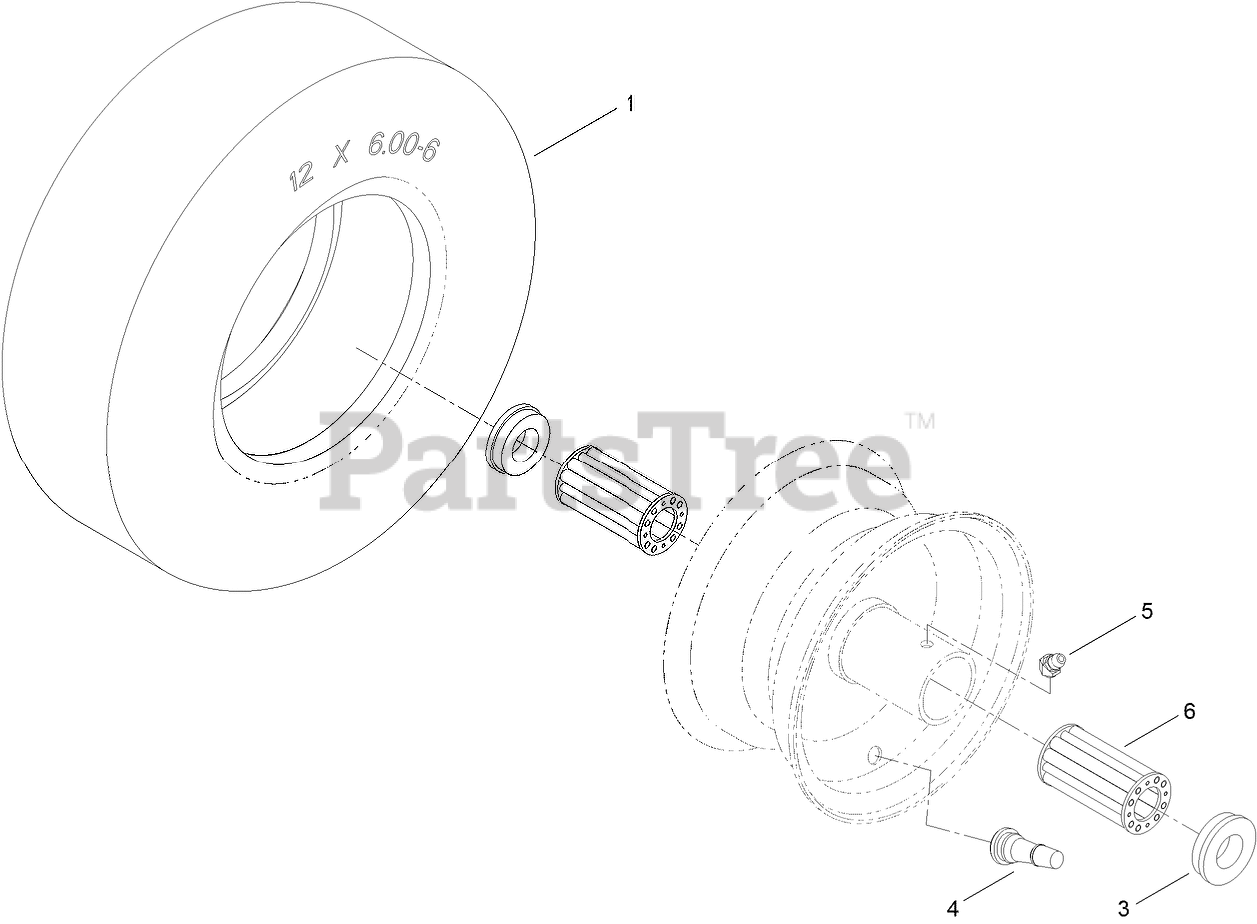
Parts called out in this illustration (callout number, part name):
3	BUSHING-FLANGE
4	VALVE
5	FITTING-ZERK
6	BEARING
